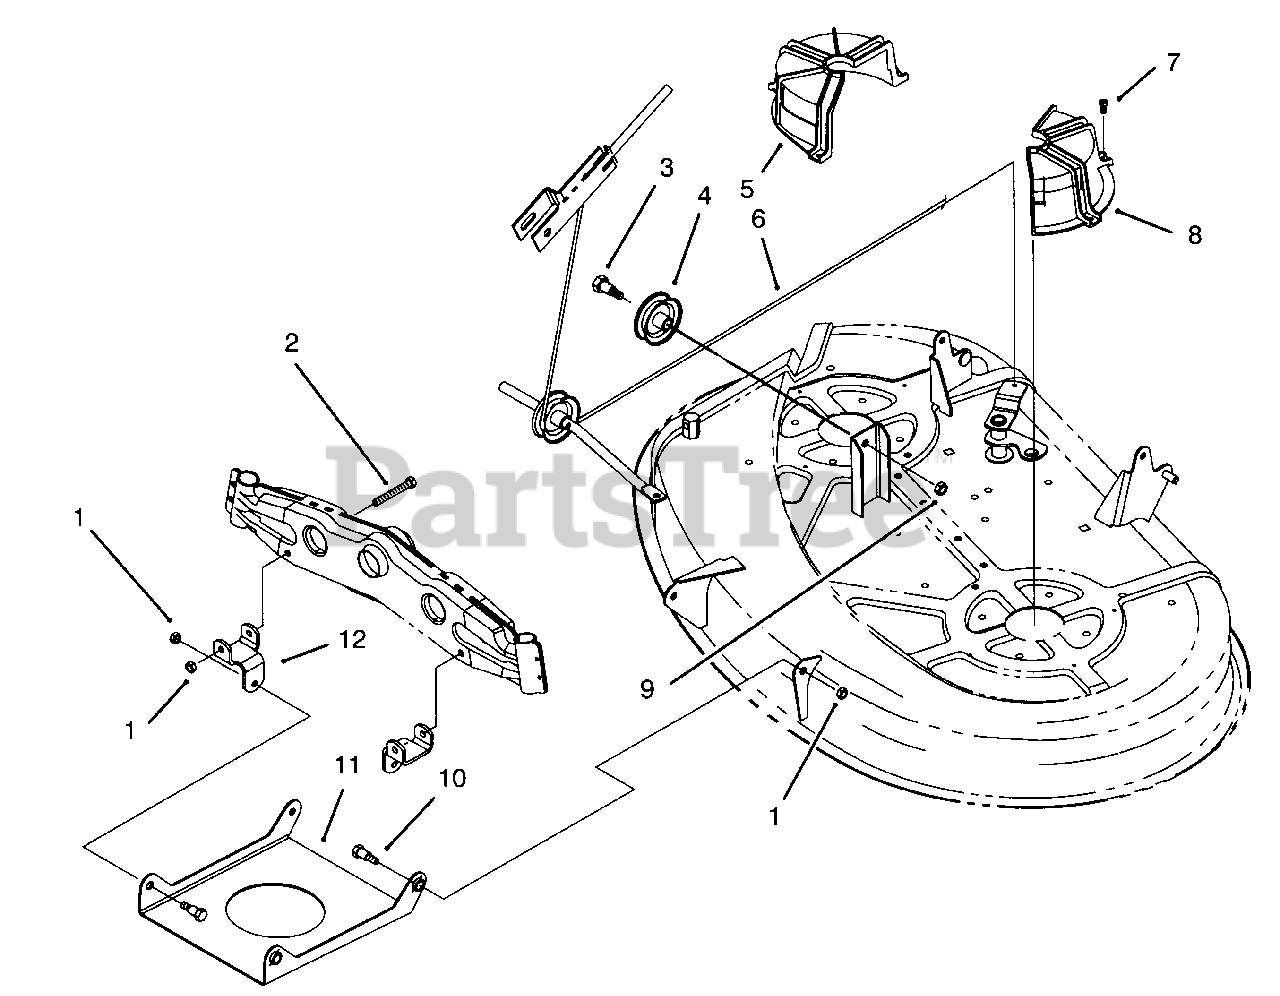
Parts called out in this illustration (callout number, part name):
1	Nut-Lock
2	Screw-Hex Hd. Cap
3	Bolt-Shoulder
4	Pulley-Cable
5	Guide-Deck Belt R.H.
6	Cable-Deck Engage
7	Screw-Thread Cutting
8	Guide-Deck Belt L.H.
9	Nut-Lock
10	Bolt-Shoulder
11	Pan-Front Deck Suspension
12	Bracket-Deck Suspension
